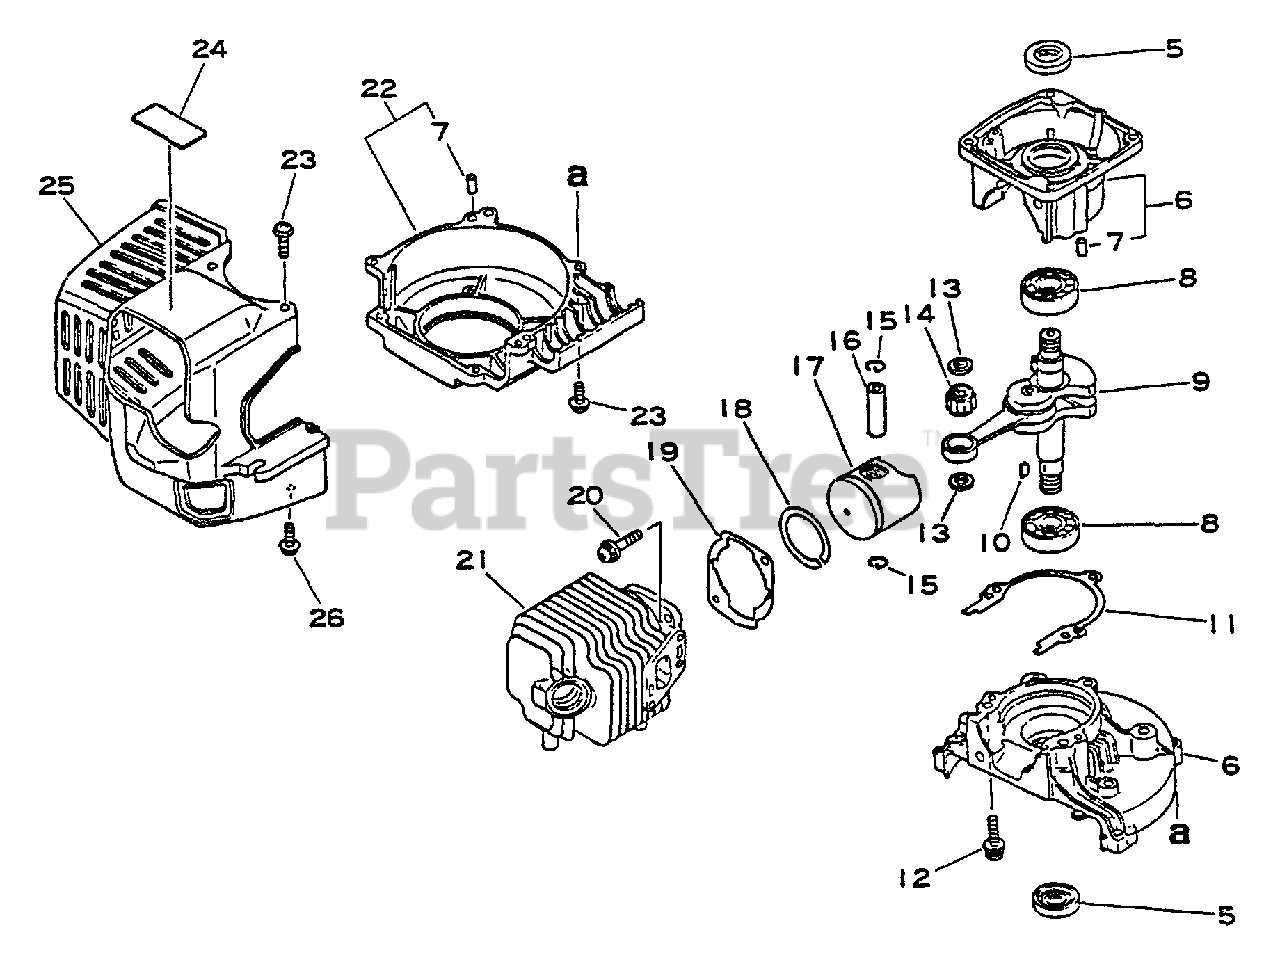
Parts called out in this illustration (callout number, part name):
5	SEAL, OIL
6	CRANKCASE KIT
7	PIN - LOCATING
8	BEARING, BALL - 6201
9	CRANKSHAFT ASSY
10	KEY
11	GASKET, CRANKCASE
12	SCREW - 5X30
13	SPACER, PISTON
14	BEARING, NEEDLE
15	RING, RETAINING
16	PIN, PISTON
17	PISTON
18	RING, PISTON
19	GASKET, CYLINDER
20	SCREW - 5X25
21	CYLINDER
22	CASE, FAN
23	SCREW - 4X14
24	LABEL - MODEL
25	COVER, ENGINE - ORANGE
26	SCREW - 4X20
